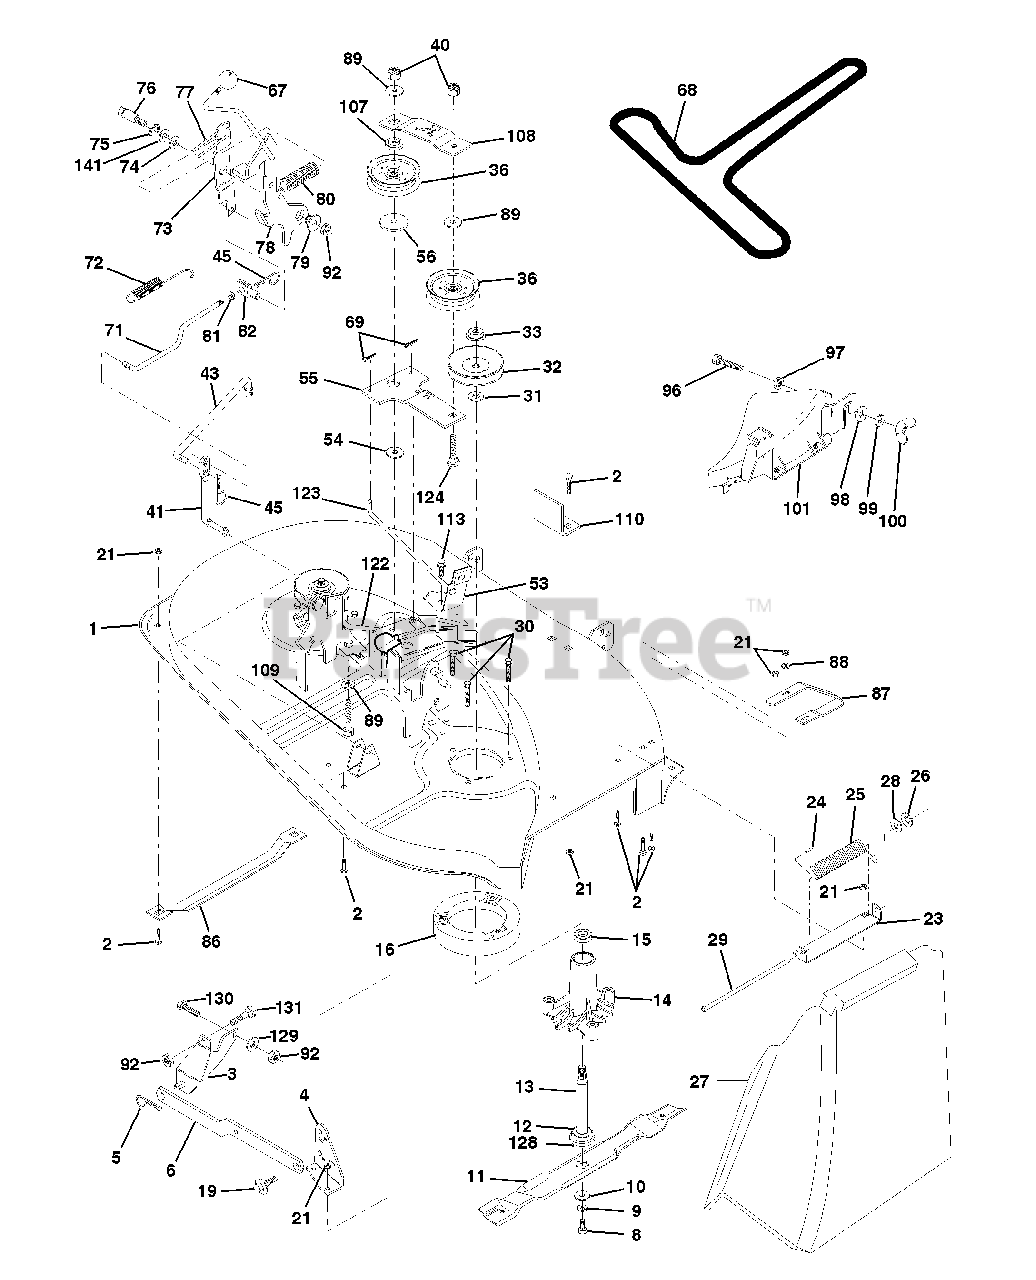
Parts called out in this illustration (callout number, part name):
1	Deck Asm Weldment
2	Bolt Rdhd Sqnk 5/16-18unc X3/4
3	Bracket Asm Fr Sway Bar 38/42
4	Bracket Asm Deck Sway Bar
5	Retainer Spring
6	Arm Suspension Rear
8	Bolt 3/8 - 24 X 1.25 Gr 8
9	Washer Lock Hvy 3/8
10	Washer Hard Blade Mower Vented
11	Blade Mower Mulching 38"
12	Bearing Ball #6024 (Mandrel)
13	Shaft Asm W/lower Bearing
14	Housing Mandrel Vented
15	Bearing Ball Mandrel
16	Stripper Mower Vented
19	Bolt Shoulder
21	Nut Crownlock 5/16-18 UNC
23	Bracket Deflector Mower
24	Cap Sleeve 80 x 112 Blk Mower
25	Spring Torsion Deflector 2 52
26	Nut Push Phos & Oil
27	Shield Deflector
28	Washer 11/32 X 5/8 X 16 Ga
30	Screw Thdrol Rolling Washer Head
31	Washer Spacer Mower Vented
32	Pulley Mandrel
33	Nut 9/16 Toplock Flng Oil Dip
36	Pulley Idler Flat 3 060
40	Nut Crownlock 3/8-16 UNC
41	Rod Pivot W/nibs
43	Rod Clutch Secondary
45	Spring Retainer 1" Zinc/cad
54	Washer Hardened
56	Spacer Retainer Pm Mower
67	Knob Rd 7/16-14 Plstc Thds Blk
68	V-Belt Mower
69	Pin, Cotter 3/32 x 3/4
71	Rod Clutch Primary 38/42
72	Spring Return
73	Arm Clutch Secondary
74	Washer 25/32 X 1-5/8 X 16 Ga
75	Ring Klip #t5304-75
76	Bolt Shoulder 3/8-16 Unc 1 44
77	Keeper Spring 4 000
78	Arm Asm Clutch Primary
79	Bushing 747 Od X 794 Lg Brass
80	Spring Clutch Mower
81	Nut Hex Jam 3/8-16
82	Trunnion Adj 94
86	Runner, LH
87	Runner, RH
88	Washer 11/32 x 3/4 x 16 Ga.
89	Washer 13/32 x 1 x 12 Ga.
92	Nut Lock Hex W/Ins 3/8-16 Unc
96	Bolt 3/8-16 x 1-1/4 Mulcher
97	Nut Crownlock 3/8-16 UNC
98	Washer 13/32 x 1-1/4 x 16 Ga.
99	Washer Lock Hvy Hlcl Spr 3/8
101	Cover Asm Mulching 38"
107	Spacer, Retainer
108	Stiffener, Idler Arm
109	Bolt, Hex Head 3/8-16 x 2-1/2
110	Upstop Deck Front 38"
113	Screw Thdrol 5/16-18 X 3/4
122	Rod, Brake, LH
123	Rod, Brake, RH
124	Bolt, Carriage 3/8-16 x 1-3/4
128	Washer Felt
129	Washer 13/32 x 13/16 x 12 Ga.
130	Bolt, Fin Hex 3/8-16 UNC x 1 Gr. 5
131	Bolt, Rdhd Sqnk 3/8-16 x 1
141	Washer Thrust .75 x 1.230
